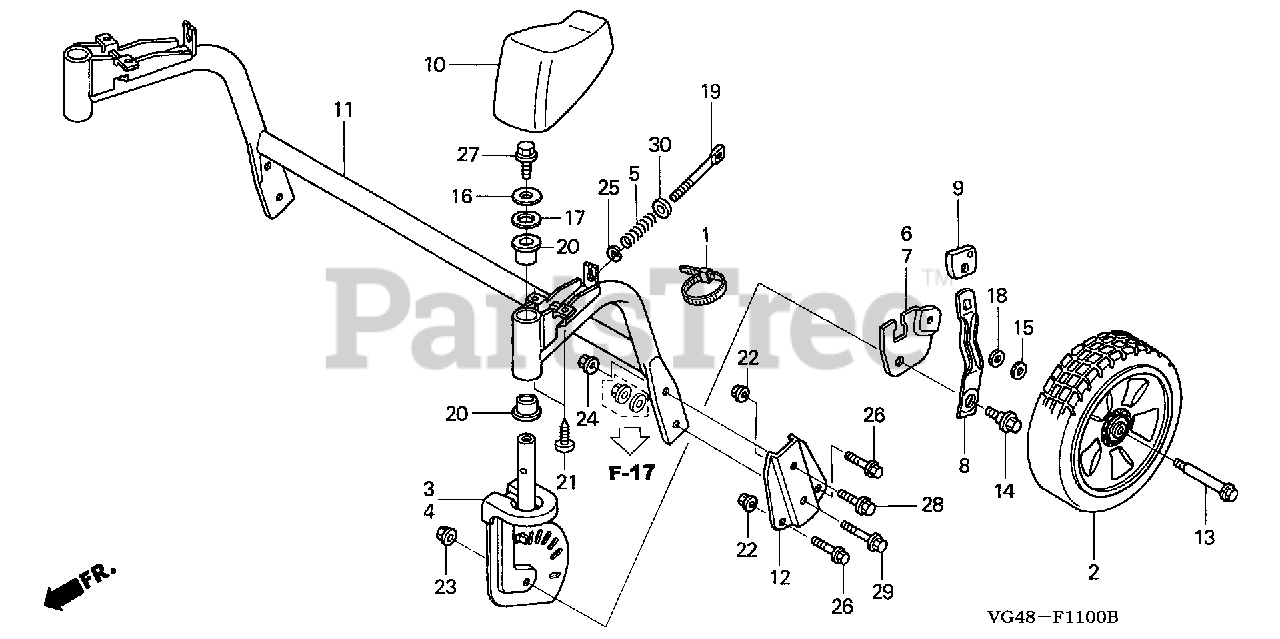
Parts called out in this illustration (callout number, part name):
1	TIE, CABLE (157.5MM)
2	WHEEL, RR.
3	CASTER, R. FR. *NH190M* (VINTAGE GRAY METALLIC)
4	CASTER, L. FR. *NH190M* (VINTAGE GRAY METALLIC)
5	SPRING, CASTER LOCK
6	ARM, R. FR. ADJUSTING
7	ARM, L. FR. ADJUSTING
8	PLATE, FR. ADJUSTER
9	GRIP, ADJUSTER
10	COVER, FR. WHEEL PIPE
11	PIPE, FR. WHEEL *NH190M* (VINTAGE GRAY METALLIC)
12	BRACKET, FR. WHEEL PIPE *NH190M* (VINTAGE GRAY METALLIC)
13	BOLT, FR. WHEEL SHAFT
14	BOLT, ADJUSTER ARM
15	WASHER, WHEEL
16	WASHER, PLAIN (8MM)
17	WASHER, CASTER
18	WASHER, THRUST (13X27X1)
20	BUSH, CASTER
21	SCREW, TAPPING (5X12)
22	NUT, FLANGE (6MM)
23	NUT, FLANGE (8MM)
24	NUT, FLANGE (8MM)
25	E-RING (5MM)
26	BOLT, FLANGE (6X14)
27	BOLT, FLANGE (8X16)
28	BOLT, FLANGE (8X16)
29	BOLT, FLANGE (8X25)
30	WASHER, PLAIN (3/16)
